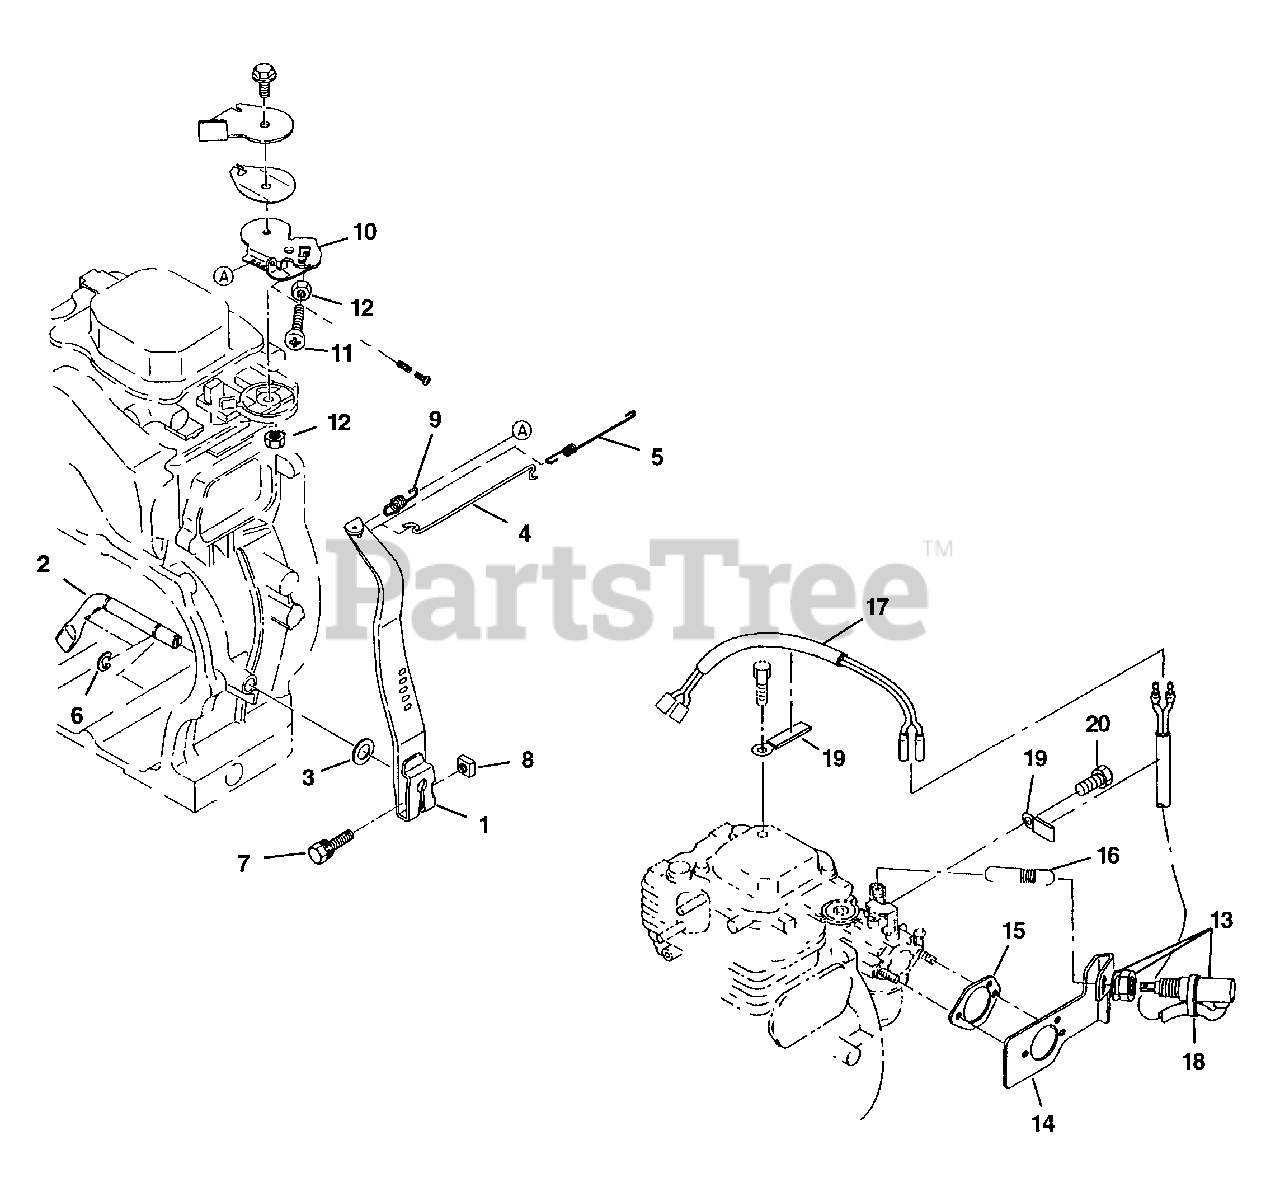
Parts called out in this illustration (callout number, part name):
1	Governor lever
2	Governor shaft
4	Governor rod
5	Rod spring
7	Bolt & washer M6 X 12
8	Nut M6 X 1.0
9	Governor spring
10	Speed control assy
11	Screw
12	Nut M6 X 1.0
13	Solenoid
14	Solenoid bracket
15	Insulator gasket
18	Wire band
20	Tapping screw
